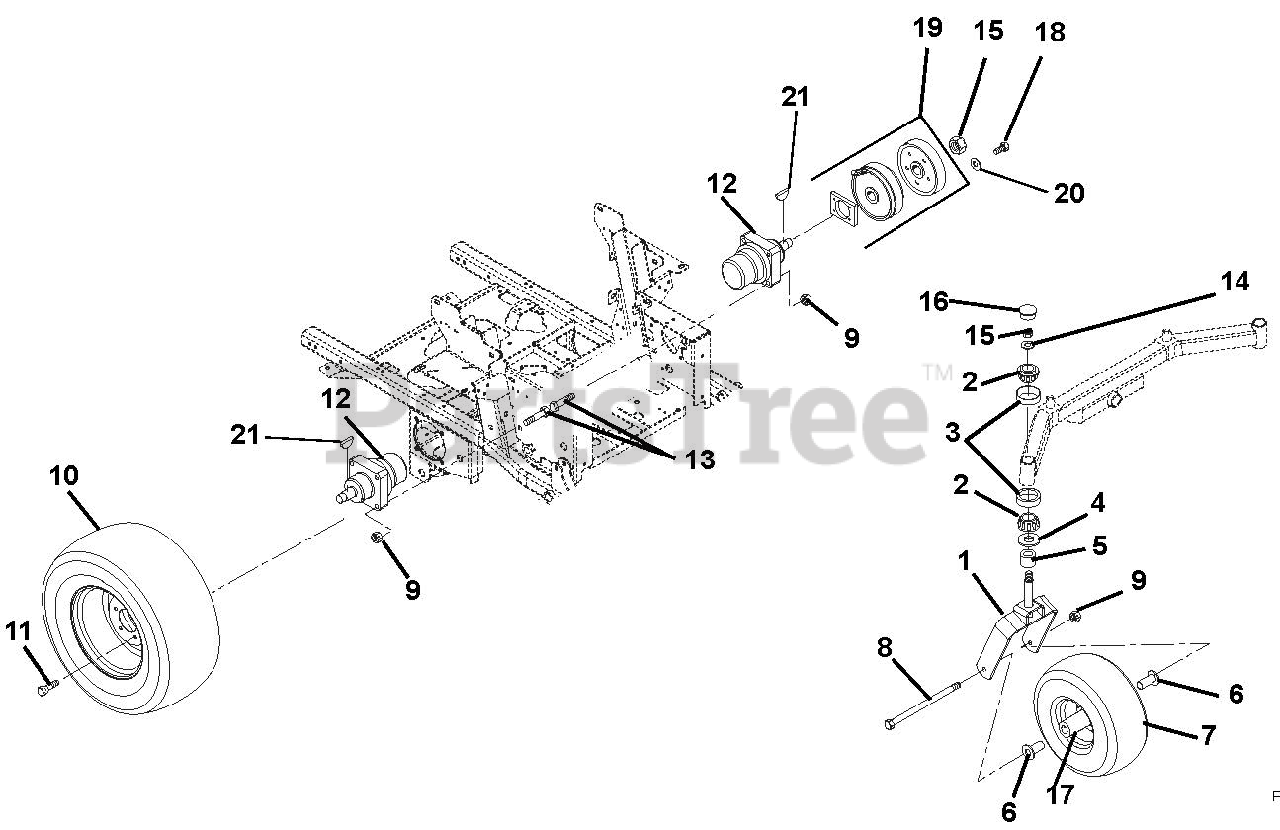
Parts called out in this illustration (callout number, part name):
1	Fork, Front
2	Bearing, Cone w/ Grease
3	Bearing, Cup 1.980 x .420
4	Bearing Seal 1.5 x 2 x .18
5	Spacer, PM, 1.03 I.D. x 1.5 O.D. x .375
6	Spacer, Wheel
7	Wheel/Tire Assembly
7	Tire, 15 x 6-6
8	Bolt, Hex .50-13 x 9.00 Grade 5
9	Nut, Locking-Top-Flange .50-13
10	Tire/Wheel Assembly, 24 x 11.50-12
10	Tire, 24 x 11.50-12
10	Tire/Wheel Assembly, 23 x 10.00-12
10	Tire, 23 x 10.00-12
11	Bolt, Lug .50-20 x 1.38
12	Wheel Motor, 18E
12	Hydraulic Wheel Motor
13	Bolt, Hex .50-13 x 2.75 Grade 8
14	Washer, Flat Steel, .812 x 1.50 x .135
15	Nut, Jam Center-Lock .75-16
16	Cap, Dust
17	Bearing, 25mm I.D. x 52mm OD x 15mm
18	Bolt, Hex .31-18 x 1.5 Grade 8 EP30
19	Kit, Parking Brake Service
20	Washer, Locking .31 x .078 Regular
21	Key, Woodruff .31 x 1.00
